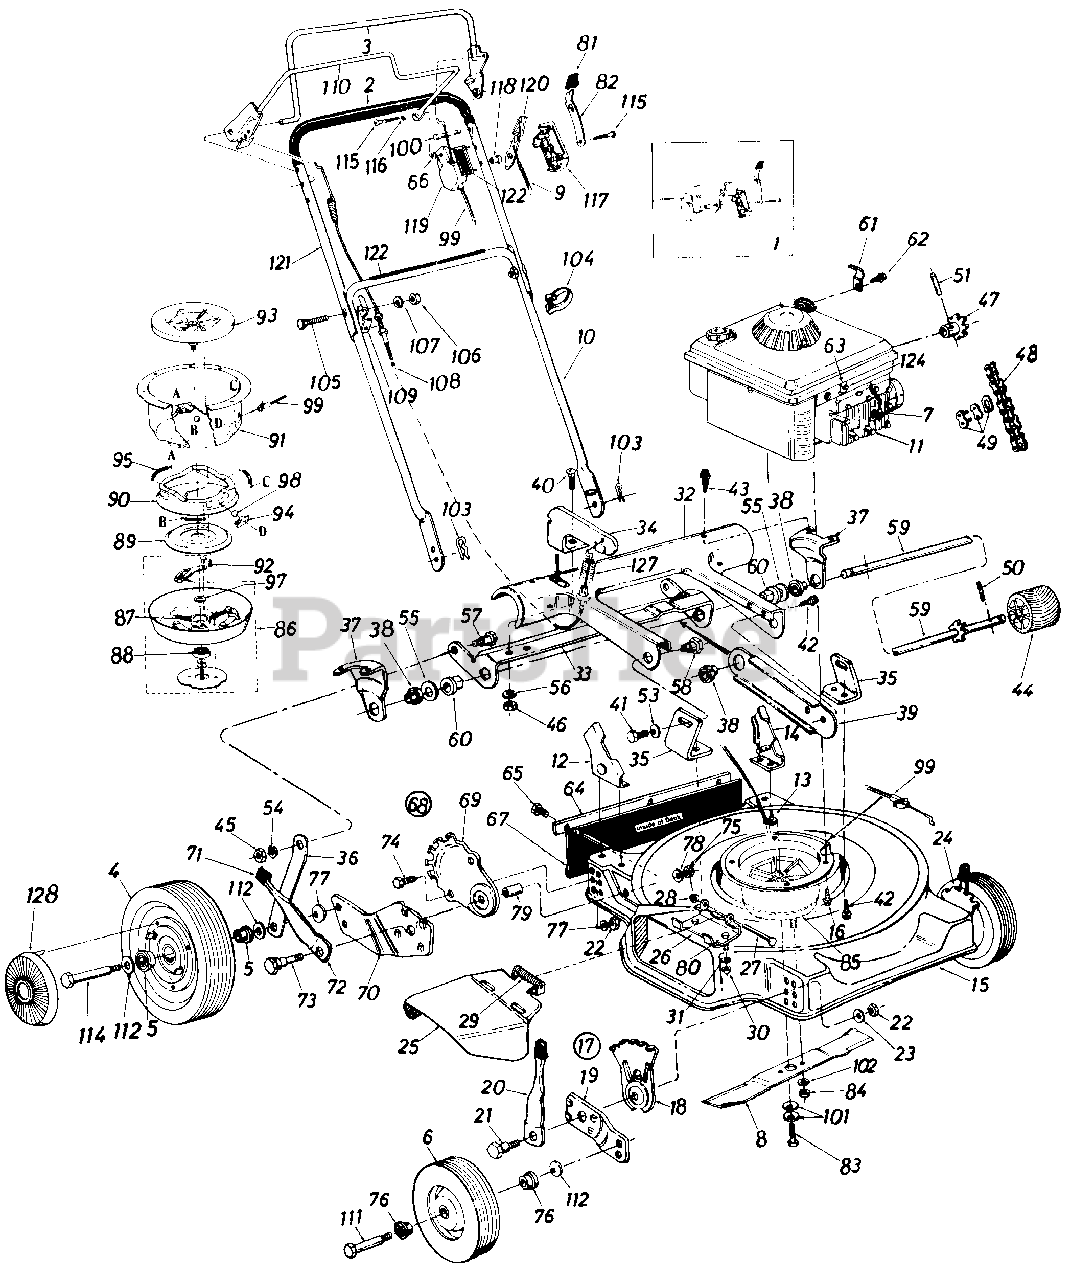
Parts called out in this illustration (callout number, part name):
1	Kit-Control Housing Comp.
3	Control Handle Ass'y. Comp.-L. H .
4	RearWheel Ass'y.-Comp. 9x 1.75
5	RearWheel Brg.
7	Spark Plug Boot
8	22" Blade
9	Throttle Control Wire-53"
10	Lower Handle (Chrome)
11	Engine
12	Handle Brkt. Ass'y.-R.H.
13	Hex Wash. Hd. "B"-Tap Scr. 5/16-18 x .50" Lg.
14	Handle Brkt. Ass'y.-L.H.
15	22" DeckAss'y.
16	Hex Wash. Hd. TT-Tap Scr. 3/8-16 x 1.00" Lg.
17	Height Adj. Ass'y. Comp.- R. H .
18	Height Adj. Plate
19	Pivot Bar
20	Spring Lever w/Knob
21	Shld. Bolt .500" Dia. x .375
22	Hex Nut 3/8-16 Thd.
23	Bell-Wash. .39" I.D. x 1.4"
24	Height Adj. Ass y. Comp.-L.H.
25	Chute Deflector Ass'y. Comp.
26	Deflector Hinge Plate Ass'y.
27	Pivot Pin
28	Push Cap 1/4" Rod
29	Torsion Spring
30	Hex Nut 1/4-2 Thd.
31	L-Wash. 1/4" I.D.
32	Pinion Pivot Cover 22"
33	Cam
34	Engagement Arm
35	Pivot Bracket
36	Link
37	Axle Brkt.
38	Flange Ball Brg. .500" I.D.
39	Brg. Support
40	Carriage Bolt 1/4-20 x .50"
41	Hex Bolt 3/8-16 x .50" Lg.
42	Hex AB-Tap Scr. 1/4 x .62"
43	Hex Wash. Hd. AB-Tap Scr. 1/4" x .62" Lg.
44	Drive Pinion
45	Hex Nut 5/16-18 Thd.
46	Hex Nut 1/4-2 Thd.
47	10 Tooth Sprocket Ass'y.
48	#48 Chain 1/2" Pitch 49 Li nks
49	Master Link
50	Spring Pin Spir. 3/16" Dia. x 1.25" Lg.
51	Spring Pin Spir. 3116" Dia. x 1.00" Lg.
53	Bell-Wash. .400" I.D. x .88"
54	L-Wash. 5/16" I.D.
55	Fl-Wash. .531" I.D. x.930"
56	L-Wash. 1/4" I.D.*
57	Shoulder Bolt .437" I.D. x 162
58	Shoulder Nut .625" Dia. x .1 65
59	Pinion Shaft w/7 Tooth Sprocket
60	Flange Brg. .506" I.D.
61	Casing Clamp
62	Hex "B" Tap Scr. #10 x .38" Lg.
63	Casing Clamp
64	Retaining Strip
65	Hex AB-Tap Scr. 1/4 x .62" Lg.
66	Fl-Wash. .203 I.D. x .406 O.D.
67	Rear Flap Ass'y.
68	Rear Height Adj. Ass'y.-Comp.-R. H.
69	Index Plate
70	Pivot Bar-R.H.
71	Spring Lever Knob
72	Spring Lever
73	Shoulder Bolt .500" Dia. x .433" Lg.
74	Hex Bolt 3/8-16 x .75" Lg.
75	Hex Cent. L-Nut 5/16-18 Thd.
76	Front Wheel Bearing
77	Bell-Wash. .400" I.D. x .88"
78	Bell-Wash. .345" I.D. x.88"
79	Spacer.383" I.D. x .503" O.D. x .562" Lg.
80	Hex Bolt 1/4-20 x 50" Lg.
81	Spring Lever Knob
82	Lockout Lever
83	Hex Bolt 3/8-24 x 200" Lg. (Grade 8)
84	Hex Nut 3/8-24 Thd. (Grade 8)
85	Blade Brake Clutch Comp.
86	Clutch Blade Housing Ass'y.
87	Compression Spring 35" O.D. x 200" Lg.
88	Ball Brg. .669" I.D. x 1.574"
89	Clutching Cone
90	Brake Cup Cone
91	Clutch Housing
92	Hex Tap L-Scr. 1/4 -20 x .75"
93	Fan Adapter
94	Ball Block
95	Extension Spring .35" O.D. x 1.75" Lg.
97	Fl-Wash. .690" I.D. x 1.060" O.D.
98	Steel Ball.500" Dia.
99	Clutch Cable-43"
100	Lock Pin .314" Dia. x 1.70"
101	Bell-Wash. .400" I.D. x.88"
102	L-Wash. 3/8" I.D.
103	Intern. Cot. Pin 5/16" Dia.
104	Cable Tie
105	Curved Carriage Bolt 5/16-18 x 1.38" Lg.
106	Hex Nut 5/16-18 Thd.
107	L-Wash. 5/16" I.D.
108	Clutch Cable w/Spring
109	Cable Mtg. Brkt.
110	Control Handle
111	Axle Bolt
112	Fl-Wash. .531" I.D. x 93"
114	Shld. Bolt.498" Dia. x 1.64
115	Truss Mach. Scr. #12 x 1 50" Lg
116	Spacer.23" I.D.
117	Control Panel Half
118	Control Disc Pin
119	Clutch Panel Half
120	Throttle Control Lever
121	Upper Handle (Chrome)
122	Control Labels
124	Hex Wash. Hd. AB-Tap Scr. #8 x .38" Lg.
127	Compression Spring .47" O.D. x 1.93" Lg.
128	Hub Cap
